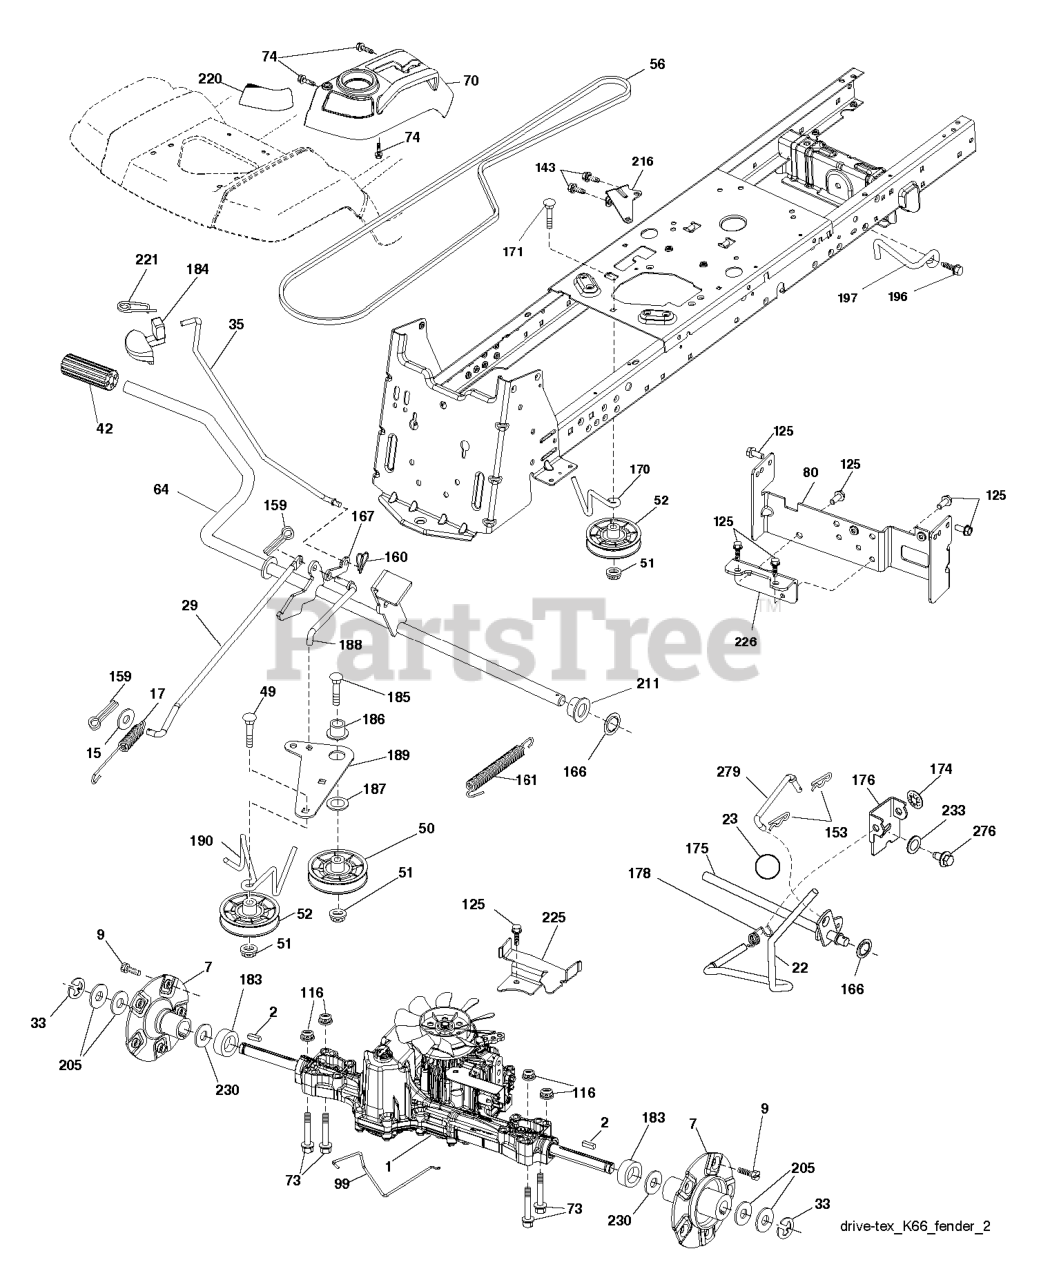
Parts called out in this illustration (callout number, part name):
2	KEY 1/4 X 2.5
7	HUB.ASM.WHEEL.REAR.23"TEX
15	WASHER
17	SPRING.BRAKE.K46
22	ROD.SHIFT.FENDER.STGT.
23	KNOB.DELUXE.(PISTOL.GRIP).BLAC
29	ROD.BRAKE.K66
33	E RING HYT
35	ROD.BRAKE.PARKING.GT.H
42	PEDAL COVER T
50	IDLER.FLAT.910.OFFSET
51	NUT LOCK FLG 3/8-16 UNC
52	IDLER.V-GROOVE.910.OFFSET
64	SHAFT.ASM.PEDAL.BRAKE.
70	RP CONSOLE.ASM.HYDO.HUSQ.
73	BOLT HEX 5/16-18 GR 5
74	SCREW.HI-LO.CONSOLE
80	STRAP.TORQUE.K66
99	ROD.SPRING.BYPASS.K66.GT.Z
116	NUT LOCK HEX FLANGE 5/16-18
125	SCREW
143	Screw 5/16-18 x 1/2 Hex, Self Tapping 5/16-18 x 1/2
153	RETAINER M
159	COTTER PIN
160	RETAINER CLIP
161	SPRING, RETURN LT
166	NUT.PUSH.625.2006
167	LATCH.BRAKE.SPRING
170	KEEPER.V-IDLER.CENTER.
174	NUT.PUSH.500.2006
175	SHAFT.ASM.SHFT.T2.TLT
176	ARM.CLEVIS.ROD.SHIFT
178	SPRING.SHIFT.GT2006
183	SPACER.AXLE.HG.TEX
184	HANDLE.PARKG.BRK.HUSQ X667
186	SPACER.RETAINER
187	WASHER 12/32X2X10GA
188	RP.LINK.CLUTCH.GROUND.DRIVE
189	BELLCRANK.GROUND.DRIVE.TEX.
190	KEEPER.BELLCRANK.DRIVE
196	SCREW 3/8-16X1
197	BRKT.ANIT-ROTATION.CLUTCH
211	BUSHING.SHAFT.BRAKE.HAND
216	BRACKET.PULLEY.IDLER.W/TEX
220	REFLECTOR.RH.TEX GT
221	RETAINER.SPRING.CLIP.H
225	KEEPER.BELT.TRANSAXLE.K66
226	BRACKET.MOUNT.TORQUE.K66.TG
233	WASHER SERRATED
276	BOLT FIN HEX 7/16-14 X 1
279	LINK.ASM.SHIFT.FENDER.K66
